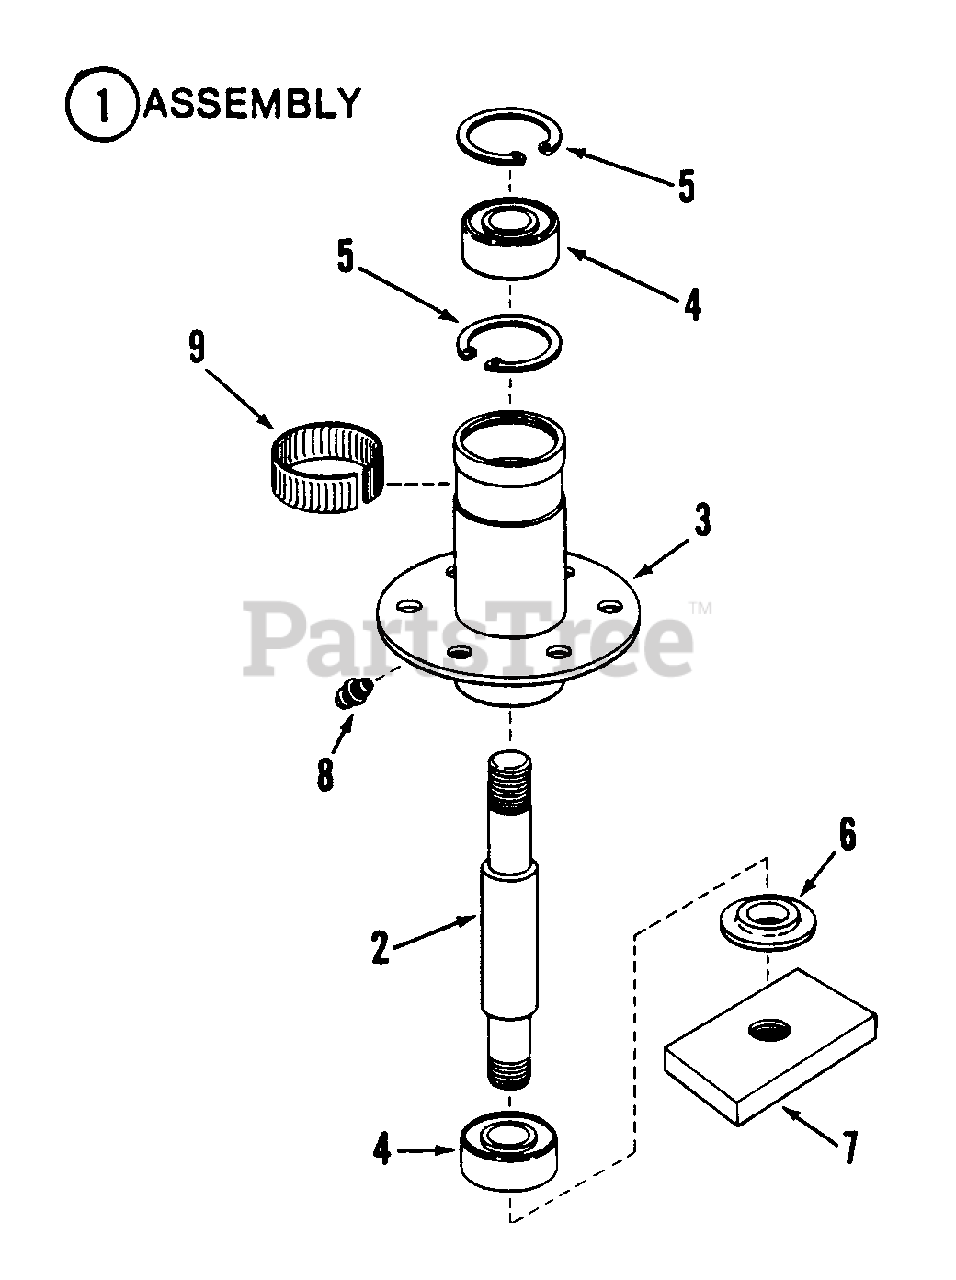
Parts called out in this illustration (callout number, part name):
1	ASSEMBLY, Spindle
2	SPINDLE, (6.06" Long)
3	HOUSING, Spindle
4	BEARING, Spindle
5	RING, Retaining
6	WASHER, Spindle
7	HOLDER, Blade
8	FITTING, Lube (Press fit for .187 hole-no ball)
9	RING, Tolerance
